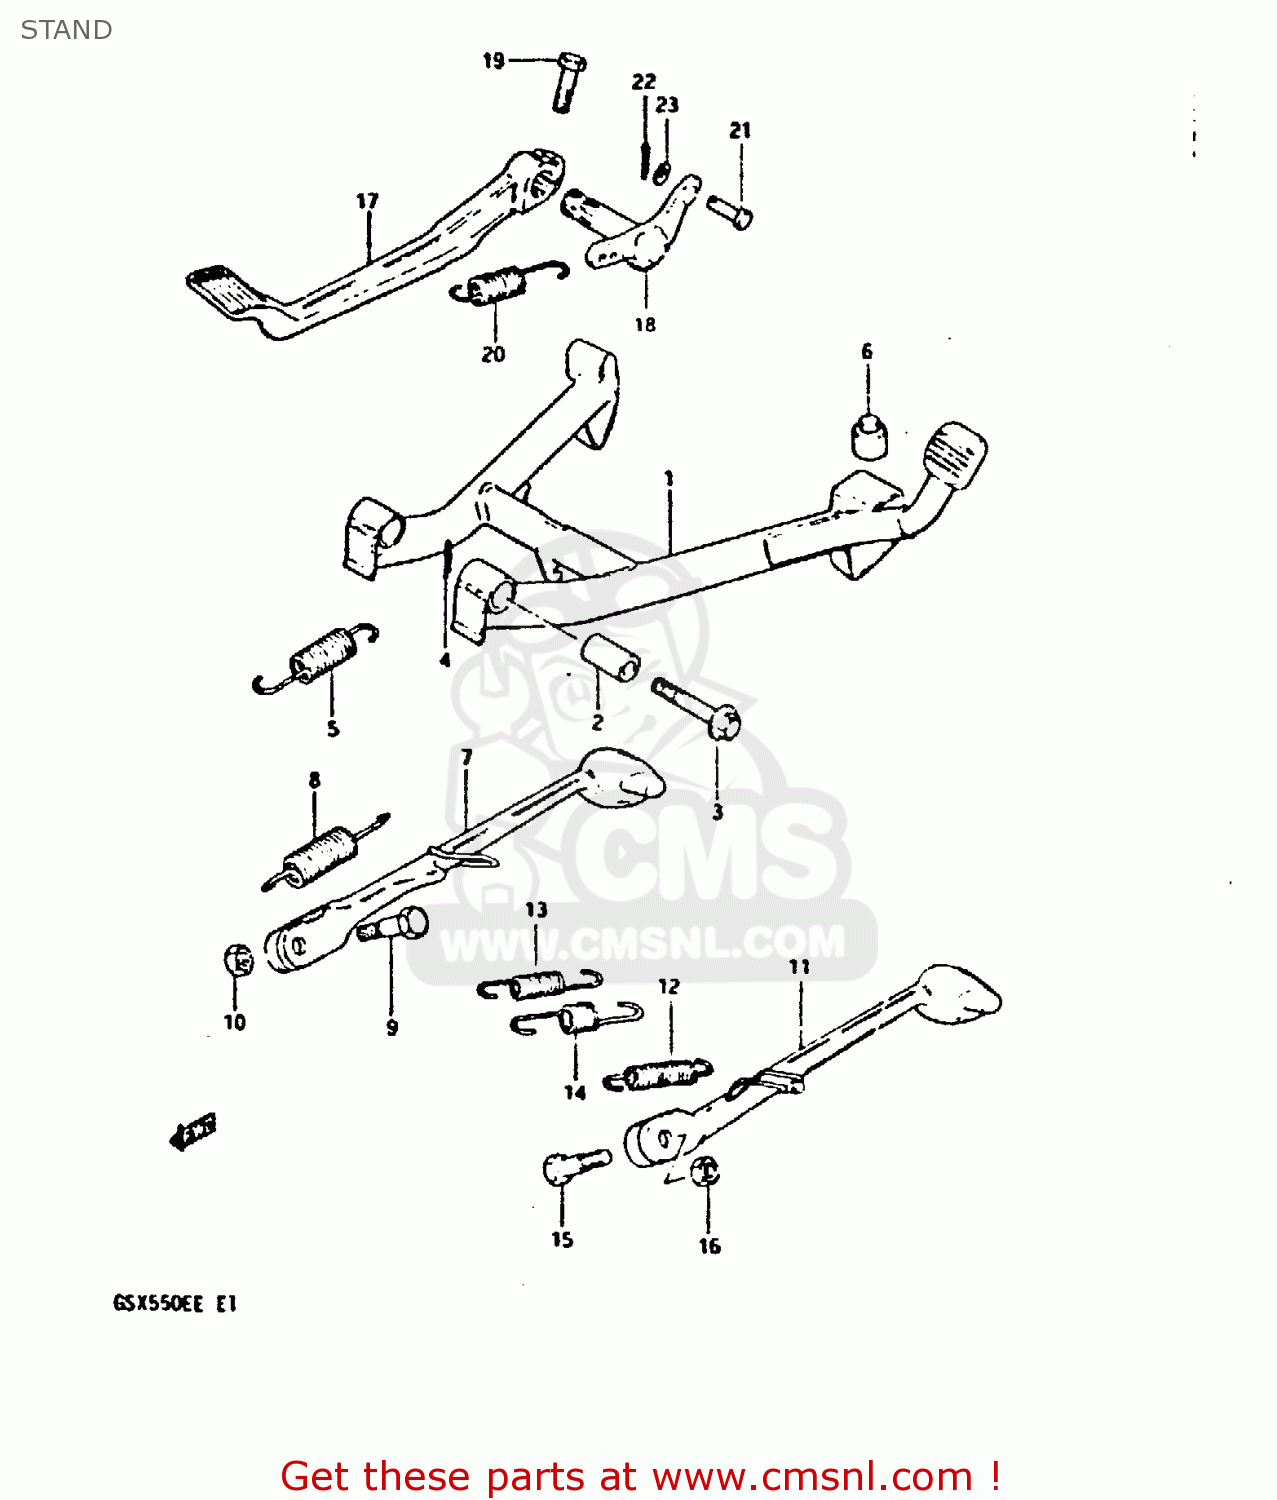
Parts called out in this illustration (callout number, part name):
1	STAND,CENTER
2	SPACER (10.5X16X31.8)
3	BOLT 10X50
4	CLIP
5	SPRING
6	CUSHION
7	STAND,SIDE
8	SPRING
9	BOLT L:30
10	NUTM10X1.25X8
17	PEDAL,BRAKE
18	ARM,BRAKE PEDAL ROD
19	BOLT
20	SPRING
21	PIN
22	PIN
23	WASHER
